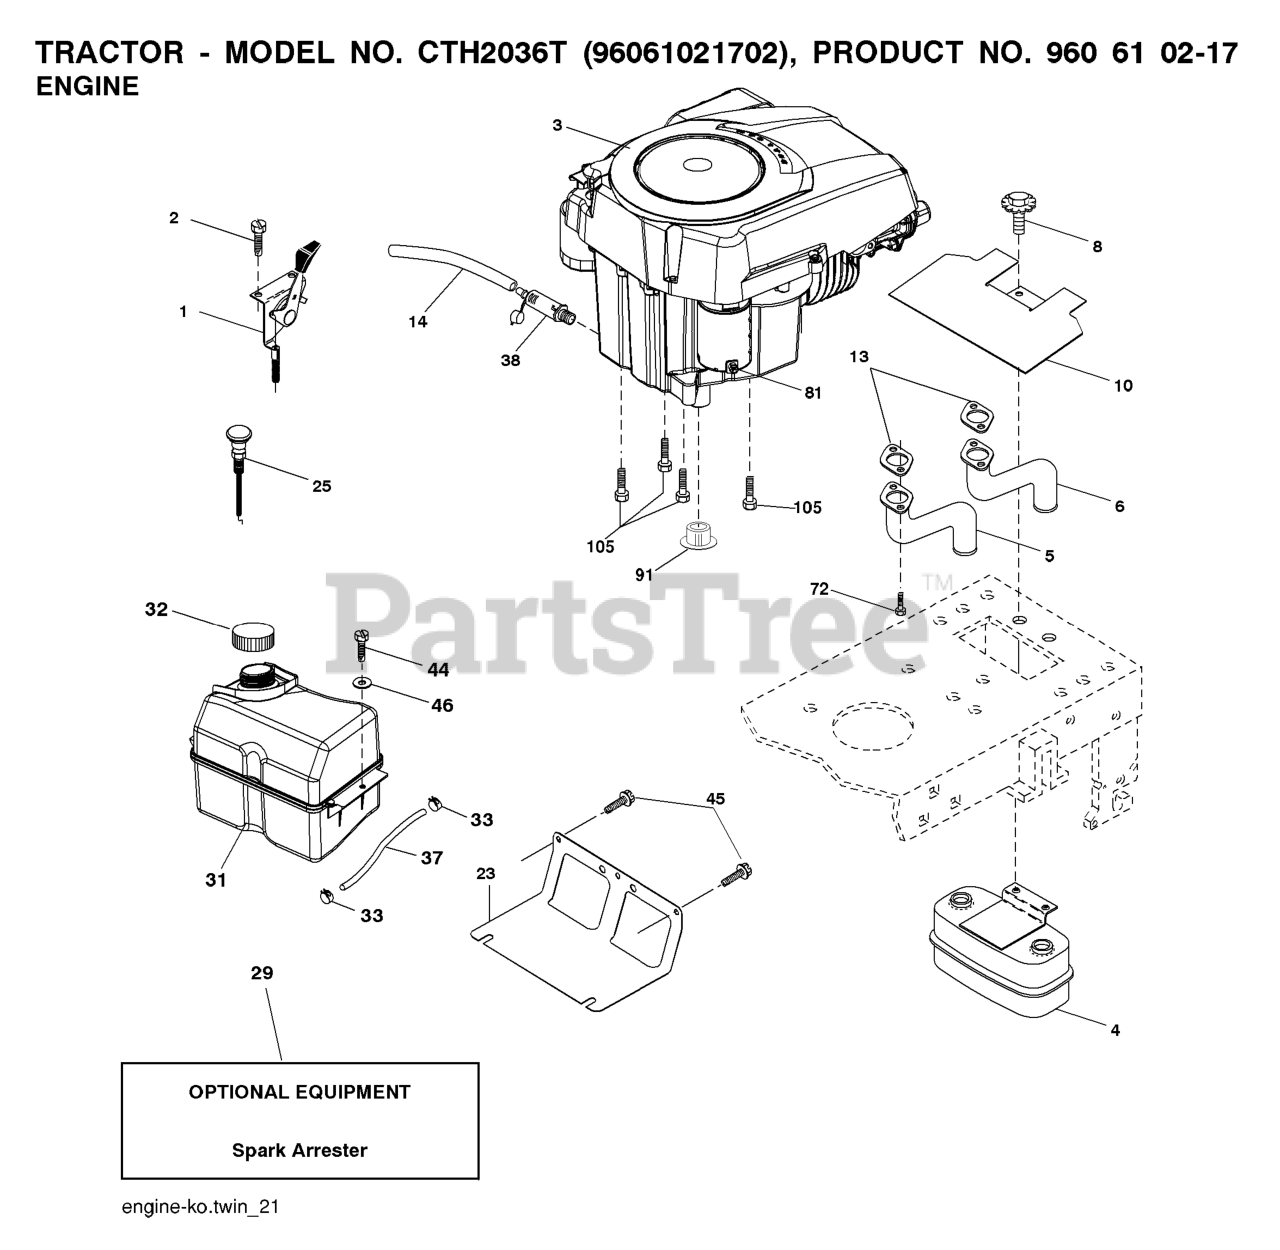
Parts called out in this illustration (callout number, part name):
1	THROTTLE CONTROL
2	SCREW.#10 X 0.750.BOS
4	MUFFLER.TWIN.CYL.LOW.TONE
5	RP.PIPE-EXHAUST LH
6	RP.PIPE-EXHAUST RH
8	BOLT.5/16-18UNCX3/4 W/SEMS.BLK
10	RP SHIELD HEAT MUFFLER
14	TUBE, DRAIN OIL ASM.
23	SHIELD.BROWNING.DBR.GUARD
25	CONTROL, CHOKE
29	KIT.SPARK ARRESTOR 794945 B&S
31	TANK.ASM.FUEL.FR.2.5GA.
32	FUEL CAP
33	HOSE CLAMP
37	LINE.FUEL.20
38	PLUG DRAIN OIL EASY
44	SCREW HEXWSHR 1/4-20X3/4
45	SCREW, 3/8-16X3/4
72	SCREW.SOCKET HD.5/16-1
81	NUT
105	SCREW 3/8-16X1
